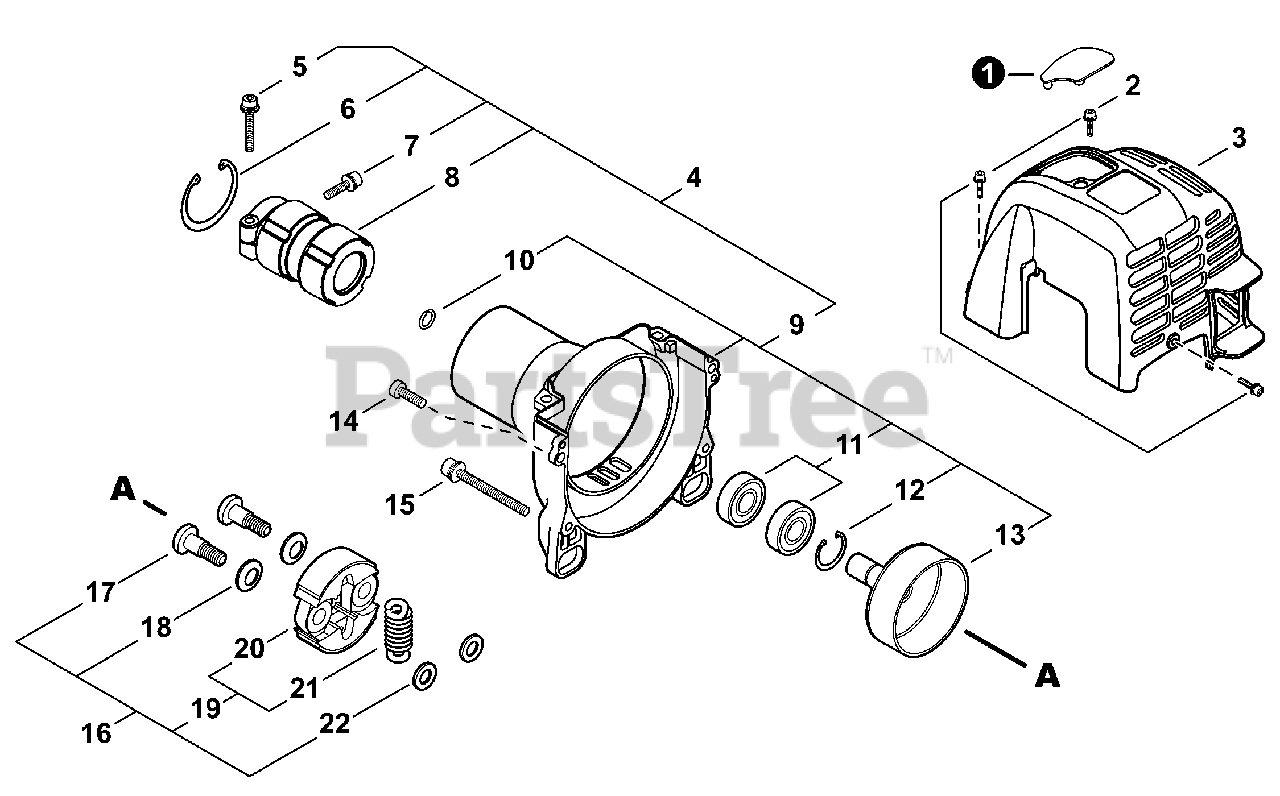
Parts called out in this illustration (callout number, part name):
1	COVER, SPARK PLUG
2	BOLT M4×14
3	COVER, ENGINE
4	COVER ASSY, FAN
5	BOLT M5×28
6	RING, SNAP Ø45
7	BOLT M5×12
8	HOLDER, MAIN PIPE
9	COVER KIT, FAN
10	RING, SNAP Ø12
11	BEARING, BALL 6001 DDU C3
12	RING, SNAP Ø28
13	DRUM, CLUTCH
14	BOLT M5×16
15	BOLT M5×40
16	CLUTCH ASSY
17	BOLT, CLUTCH
18	WASHER, SPRING
19	SHOE ASSY, CLUTCH
20	SHOE, CLUTCH
21	SPRING, CLUTCH
22	WASHER 6 MM
